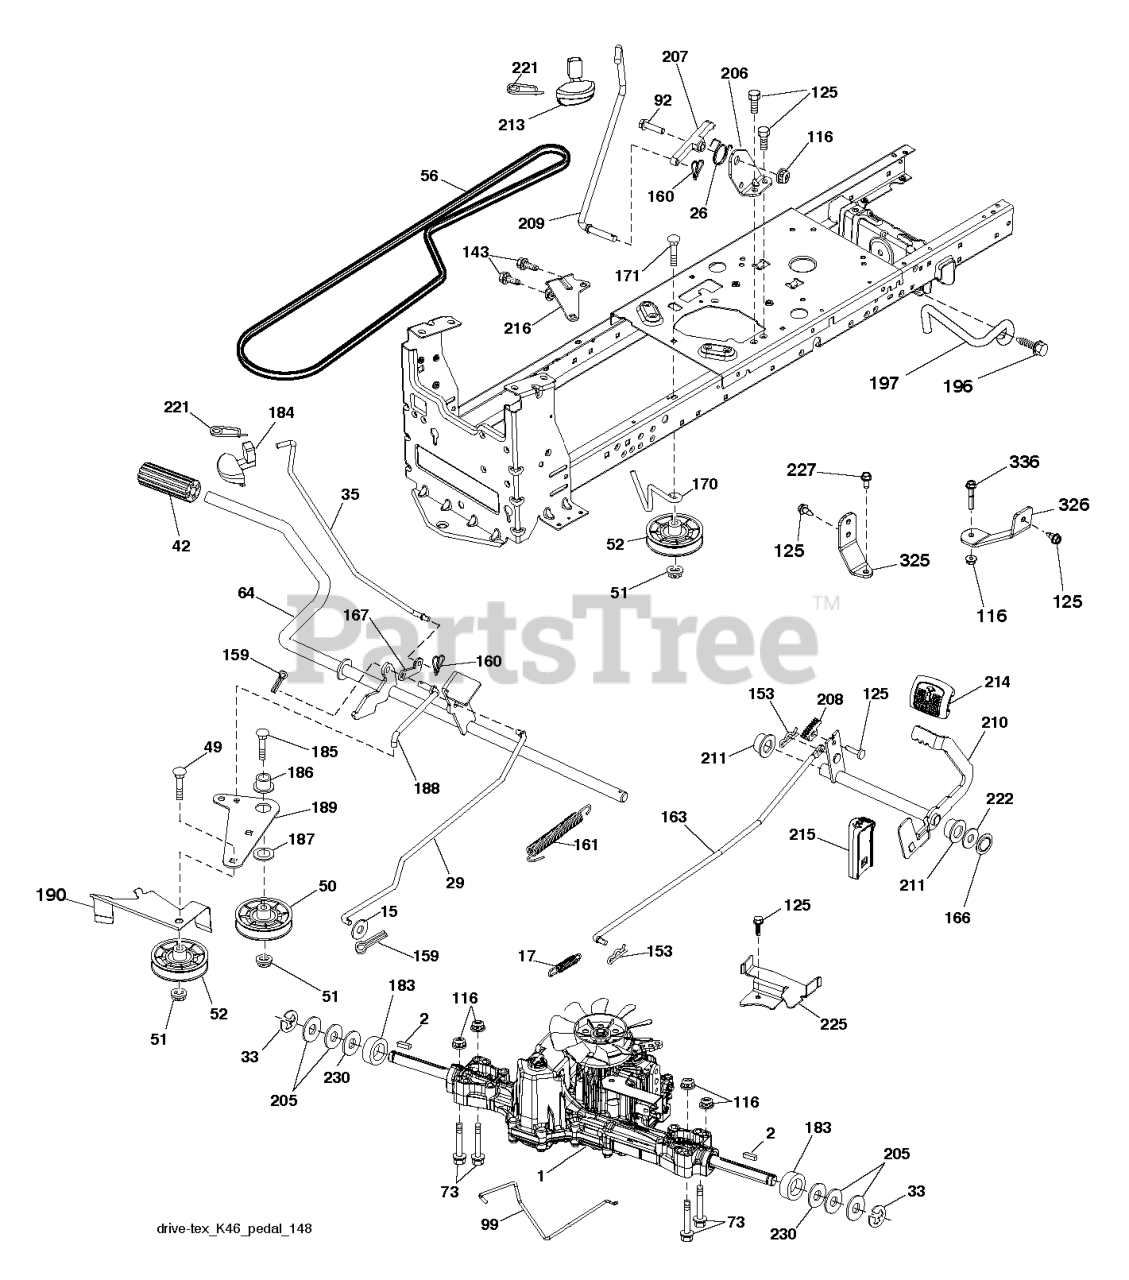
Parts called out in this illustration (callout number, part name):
2	SQUARE KEY
15	WASHER
17	SPRING.BRAKE.K46.GREEN
26	SPRING.RETURN.CRUISE
29	ROD.BRAKE.K46
35	ROD .BRAKE. PARKING. GT. HUSQ.
42	PEDAL COVER T
50	IDLER.FLAT.910.OFFSET
51	NUT LOCK FLG 3/8-16 UNC
52	IDLER.V-GROOVE.910.OFFSET
56	V-BELT.MOWER.92.40.42/K46
64	SHAFT.ASM.PEDAL.BRK.CNTR
80	STRAP.TORQUE.K46.K57R.TT
92	BOLT
99	ROD.SPRING.BYPASS.K46.LT.Z
116	NUT LOCK HEX FLANGE 5/16-18
125	SCREW
143	SCREW LT
153	RETAINER M
159	COTTER PIN
160	RETAINER CLIP
161	SPRING, RETURN LT
163	ROD.CONTROL.K57R.K46
166	NUT.PUSH.625
167	LATCH.BRAKE.SPRING
170	KEEPER.V-IDLER.CENTER.
183	SPACER AXLE
184	RB HANDLE.PARKG.BRK.HUS/PRED
186	SPACER.RETAINER
187	WASHER 12/32X2X10GA
188	RP LINK.CLUTCH.GROUND.DRIVE
189	BELLCRANK.GROUND.DRIVE.TEX.
190	KEEPER.BELLCRANK.DRIVE
196	SCREW 3/8-16X1
197	LINK.CLUTCH.ANIT-ROTAT
206	BRACKET.MOUNT.CRUISE.LATCH
207	LATCH.CONTROL.CRUISE
208	GEAR.SECTOR.CONTROL.CR
209	ROD.CONTROL.CRUISE.GT.
210	ROCKER.ASM.PEDAL.CONTR
211	BEARING.NYLON
213	KNOB.CONTROL.CRUSIE.HU
214	PEDAL.FORWARD.PAD.TEX
215	PEDAL.REVERSE.TEX.GT.4
216	BRACKET.PULLEY.IDLER.W/TEX
221	RETAINER.SPRING.CLIP.H
222	WASHER 21/32 X 1-1/4 X 10 GA.
225	KEEPER.BELT.TRANSAXLE.K46
226	BRACKET.MOUNT.TORQUE.K46.TLT
227	SCREW
230	WASHER.HARDENED
